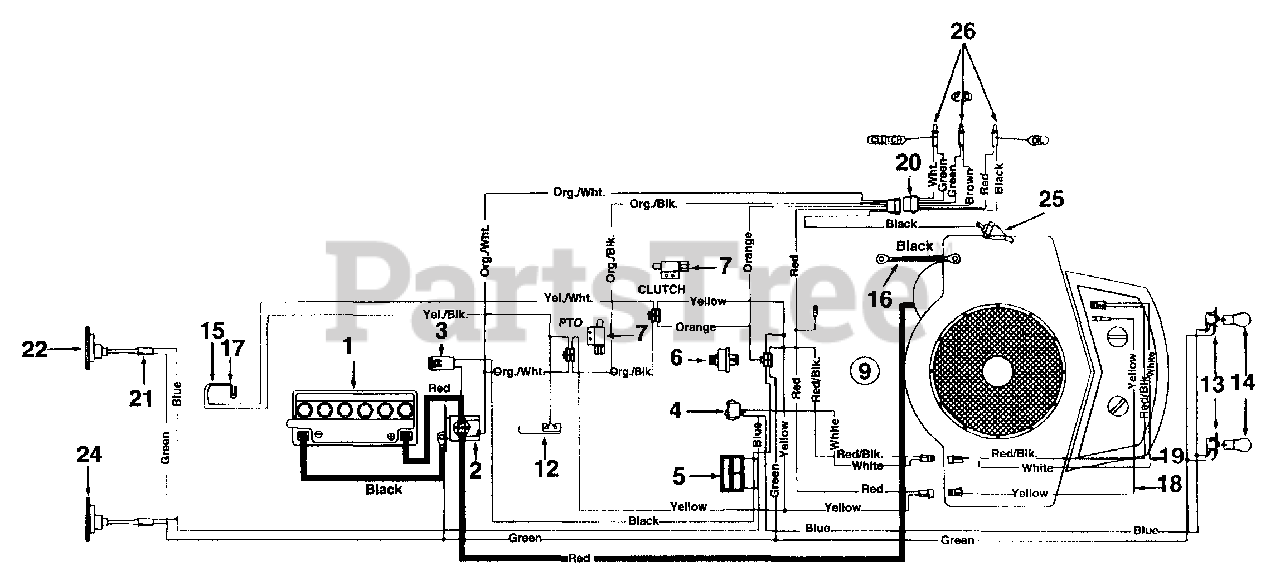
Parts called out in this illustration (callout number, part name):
1	Battery
2	Solenoid
3	Fuse 7.5 Amps
4	Light Switch
5	Ammeter
6	Ignition Switch
7	Safety Switch
9	Wire Harness
12	Safety Switch (Reverse)
13	Socket
14	Bulb (Headlight)
15	Safety Switch (Seat)
16	Ground Wire 7.5" Lg.
17	Safety Switch (Seat)
18	Harness Adapter
19	Harness Adapter
20	Harness Adapter (Monitor)
21	Tail light Harness
22	Tail light
24	Bulb (Tail light)
25	Oil Pressure Switch
26	Bulb (Monitor)
